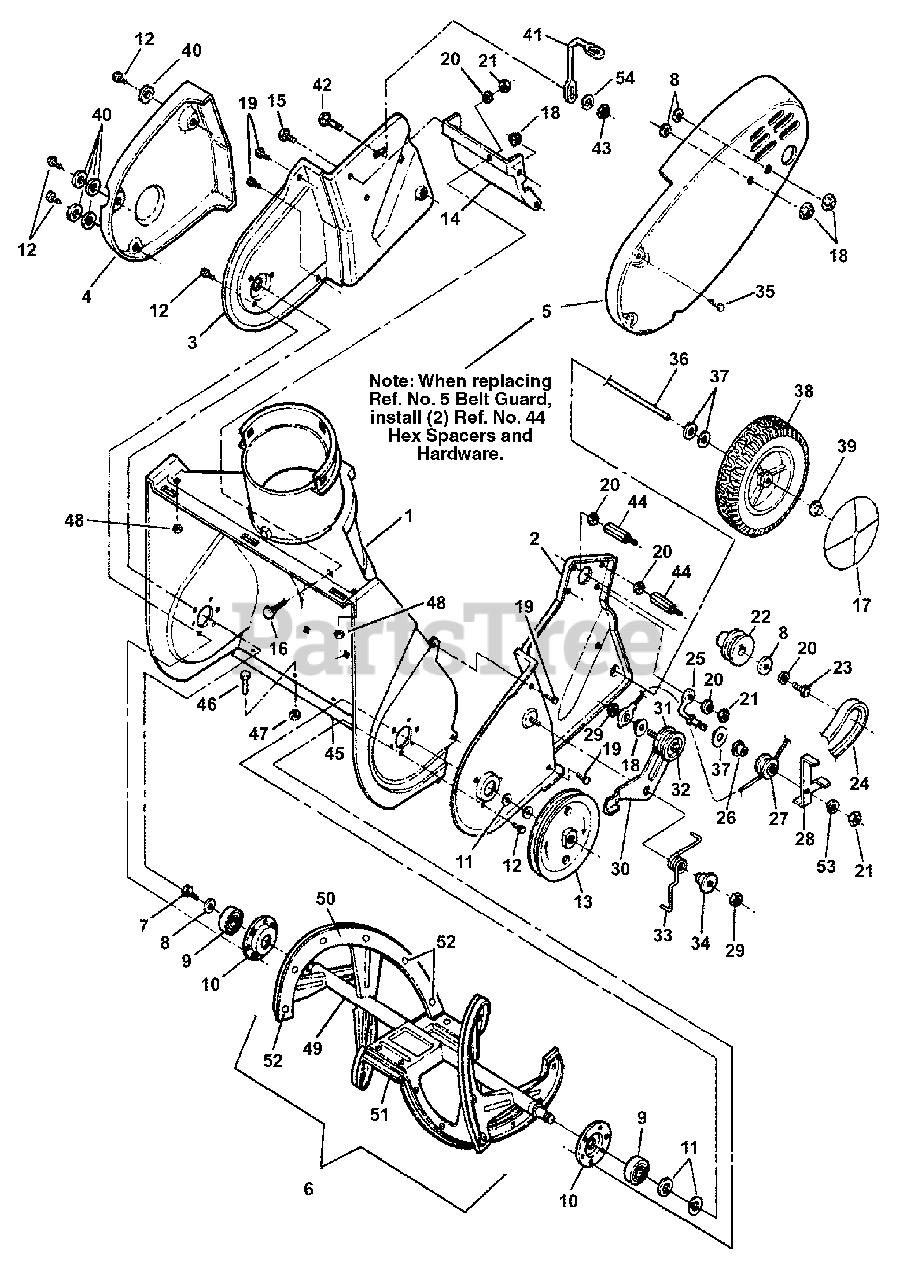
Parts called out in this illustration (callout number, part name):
1	ASSEMBLY, Auger Housing, Electric Start
1	ASSEMBLY, Auger Housing, Manual Start
2	ASSEMBLY, End Frame, L.H.
3	FRAME, End, R.H.
4	COVER, R.H. Side
5	GUARD, Belt Drive
6	ASSEMBLY, Auger (Includes Items 49 Thru 52)
7	CAPSCREW, 5/16-18 x 5/8" Taptite
8	WASHER, 5/16 Flat
9	BEARING, Ball
10	RETAINER, 1-3/4" O.D. Bearing
11	WASHER, 3/4 Flat
12	SCREW, #10-32 x 3/8" Taptite, Torx
14	BRACE, Engine
15	SCREW, 1/4-20 x 3/8" Hex Washer Taptite
16	BOLT, 5/16-18 x 3/4" Square Neck Carriage, Grade 5
17	COVER, Wheel
18	NUT, 5/16-18 Hex Flange Lock
19	SCREW, 1/4-15 x 1" Hex Washer Taptite
20	WASHER, 5/16
21	NUT, 5/16-18 Hex, Grade B or 5
22	PULLEY, Engine
23	SCREW, 5/16-24 x 3/4" Hex Head Cap, Grade 5
24	V-BELT, 3L, 34.27
25	GUIDE, Cable
26	BUSHING, Flange
27	PULLEY, Nylon
28	GUIDE, Belt
29	NUT, 5/16-18 Hex Center Lock
30	BRACKET, Idler Pivot
31	PULLEY, Idler
32	SCREW, 5/16-18 x 1-3/4" Hex Cap, Grade 5
33	SPRING, Idler Torsion
34	BUSHING, Pivot
35	SCREW, #10-16 x 3/4" Pan Head Taptite
36	AXLE, 3/8" Diameter Wheel
37	WASHER, 3/8 Flat
38	WHEEL, 7"
39	NUT, 3/8" Push
40	WASHER, #10 Flat
41	SUPPORT, Fuel Tank
42	BOLT, 1/4-20 x 5/8" Short Neck Carriage, Grade 5
43	NUT, 1/4-20 Hex, Nyloc
44	SPACER, Hex, 3.69" Long
45	BLADE, Scraper
46	SCREW, 1/4-20 x 1/2" Machine
47	NUT, 1/4-20 Hex Center Lock, Grade B or 5
48	NUT, 1/4-20 Hex Center Lock
49	STRUCTURE, Auger
50	SHOE, Flite
51	SHOE, Center Flite
52	CAPSCREW, #10-24 x 11/2" Hex Washer Taptite Sems
53	WASHER, 5/16 Internal Tooth Lock
54	WASHER, 1/4 Split Lock
